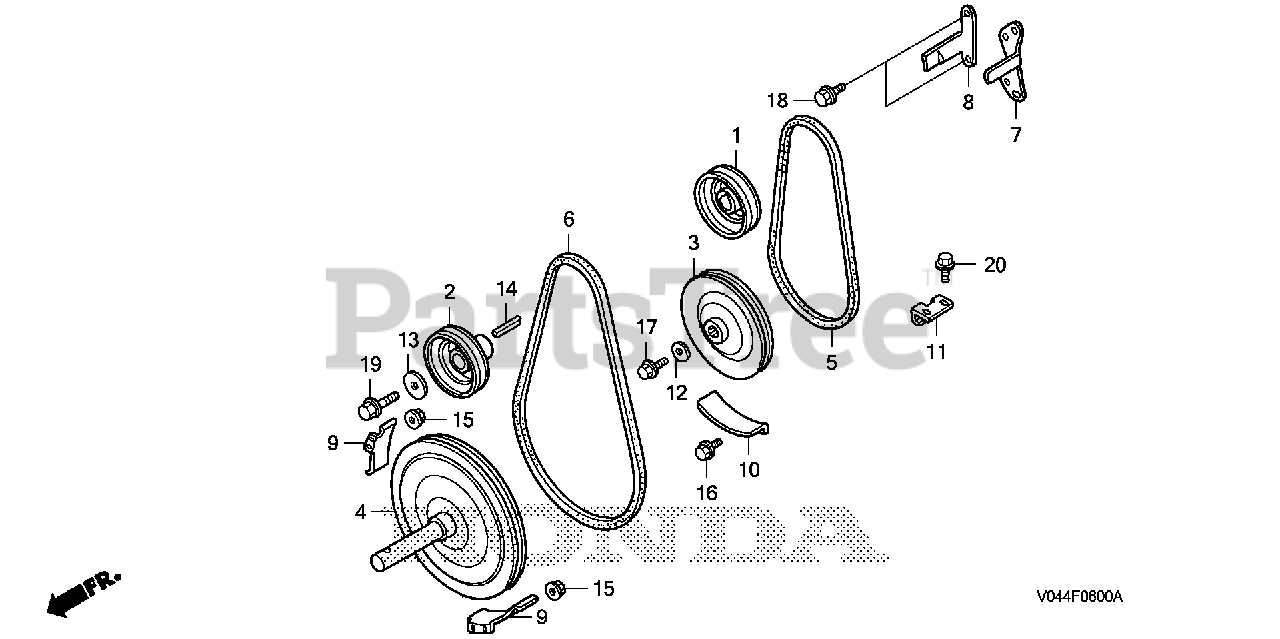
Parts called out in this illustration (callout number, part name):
1	PULLEY, WHEEL DRIVE
2	PULLEY, AUGER DRIVE
3	PULLEY, WHEEL DRIVEN (133MM)
4	PULLEY, AUGER DRIVEN (198MM)
5	V-BELT (SA-27)
6	V-BELT (LB-33)
7	STOPPER, R. BELT
8	STOPPER, L. BELT
9	STOPPER, AUGER BELT
10	PROTECTOR, BELT (WHEEL)
11	GUIDE, BELT
12	WASHER, CAMSHAFT SIDE
13	WASHER, LOCK (8.5X35X4.5)
15	NUT, FLANGE (6MM)
16	BOLT, FLANGE (6X12)
17	BOLT, FLANGE (6X16)
18	BOLT, FLANGE (8X16)
19	BOLT, FLANGE (8X28)
20	BOLT, FLANGE (6X12)
